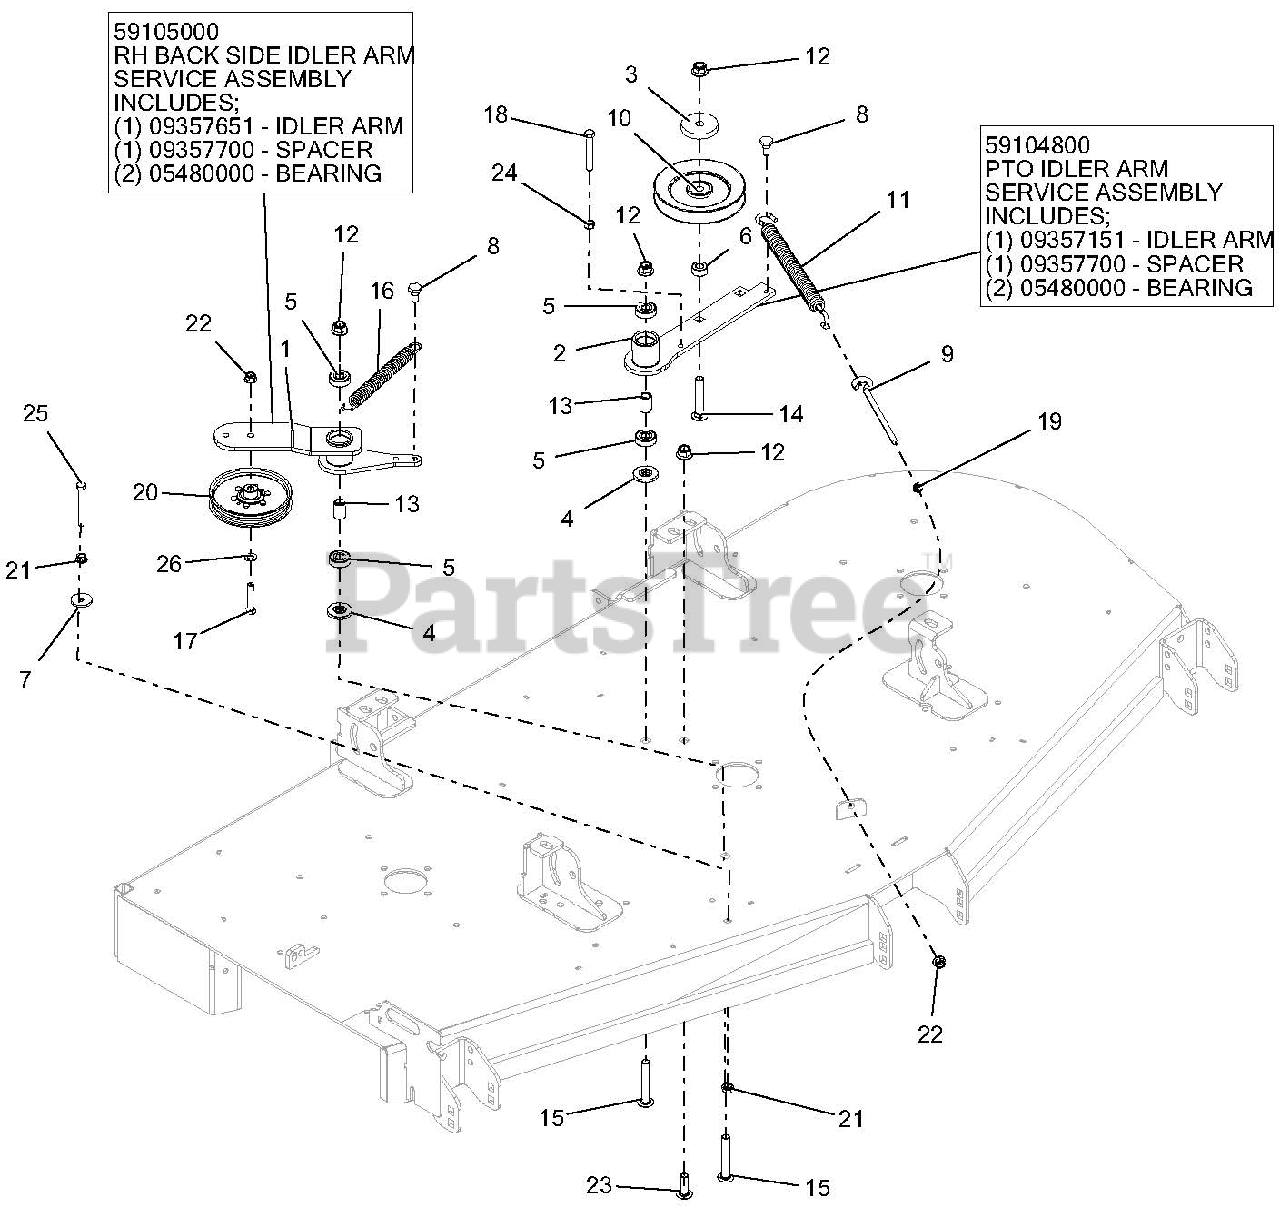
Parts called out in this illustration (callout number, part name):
1	WLDMT, DECK RH IDLER ARM
1	PTO IDLER ARM SERVICE ASSEMBLY
1	IDLER ARM
1	SPACER
1	BEARING
2	WLDMT, DECK PTO IDLER ARM-BLACK
2	PTO IDLER ARM SERVICE ASSEMBLY
2	IDLER ARM
2	SPACER
2	BEARING
3	CAP, IDLER BEARING SEALING
4	SPACER, IDLER ARM
5	BRG-BALL .500X1.375X.44
6	BSHG, SPCR .502 X .997.50 PM
7	WSHR-FL-STL .406X1.375X.135 YZ
8	BLT, SHLDR EP .38-16X.30 HEX YZ
9	BOLT, .38-16X6.00 .62 DIA EYE
10	SHEAVE, .50" ID X 6.00" OD V-IDLER
11	SPRG, EXTENSION
12	NUT-LK-NYL-FLG .50-13 YWZC
13	SPACER, .510 X .750 X 1.148
14	BLT-RDHDSQNK .50-13X3.00YG5
15	BLT-RDHDSQSHNK .50-13X3.25 YWZC
16	SPRG, EXTENSION .120X.845X6.55 WLD
17	BLT-HEX .38-16X2.00 GR5 YWZC
18	BLT-HEX .38-16X2.75 GR5 YWZC
19	NUT, JAM .375-16 YWZC
20	PULLEY, FLAT IDLER .500 X .375 W/BRG
21	@NUT-SPNLK-FLG .375-16 YWZC
22	NUT-LK-NYL-FLG .38-16 YWZC
23	BLT-RDHDSQSHNK .50-13X1.50 YWZC
24	NUT-HEX .38-16 YWZC
25	BLT-HEX .38-16X3.00 GR5 YWZC
26	WSHR-FL-STL.406X.812X.065 YWZ
